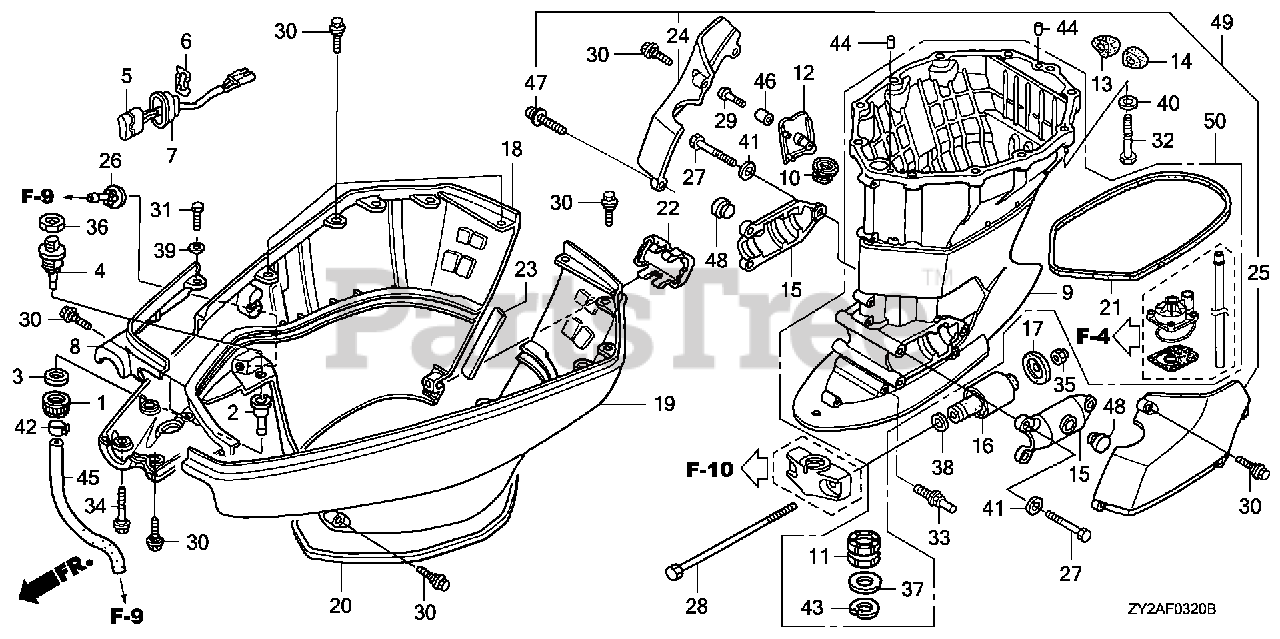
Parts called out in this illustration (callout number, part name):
1	NUT, WATER MOUTH
2	JOINT, WATER HOSE
3	SEAT, WATER MOUTH
4	CAP, WATER JOINT
5	SWITCH ASSY., POWER TILT
6	STAY, POWER TILT SWITCH
7	GROMMET, POWER TILT SWITCH
8	COVER, FR. SEPARATE *NH282MU* (OYSTER SILVER METALLIC-U)
9	CASE, EXTENSION *NH282MU* (XL) (OYSTER SILVER METALLIC-U)
10	RUBBER, DRAIN PLUG
11	BUSH, VERTICAL SHAFT
12	COVER, DRAIN PLUG *NH282MU* (XL) (OYSTER SILVER METALLIC-U)
13	SEAL, R. IDOL PORT
14	SEAL, L. IDOL PORT
15	HOUSING, MOUNTING (LOWER)
16	MOUNT, RUBBER (LOWER)
17	STOPPER, MOUNT (LOWER)
18	COVER, R. ENGINE (LOWER) *NH282MU* (OYSTER SILVER METALLIC-U)
19	COVER, L. ENGINE (LOWER) *NH282MU* (OYSTER SILVER METALLIC-U)
20	SEAL A, COVER (LOWER)
21	SEAL B, COVER (LOWER)
22	CAP, COVER (LOWER) *NH282MU* (OYSTER SILVER METALLIC-U)
23	SEAL C, COVER (LOWER)
24	COVER, R. MOUNTING (LOWER) *NH282MU* (XL) (OYSTER SILVER METALLIC-U)
25	COVER, L. MOUNTING (LOWER) *NH282MU* (XL) (OYSTER SILVER METALLIC-U)
26	GROMMET, WATER CHECK
27	BOLT, HEX. (10X35)
28	BOLT, HEX. (14X180)
29	SCREW, SPECIAL (6X35)
30	BOLT, SPECIAL (6X17)
31	BOLT, HEX. (6X25)
32	BOLT, HEX. (12X50)
33	BOLT, SPECIAL (6X12)
34	BOLT, SPECIAL (6X37)
35	NUT, SELF-LOCK (14MM)
36	NUT, HEX. (16MM)
37	WASHER (30MM)
38	WASHER, PLAIN (14MM)
39	WASHER (6MM)
40	WASHER, PLAIN (12MM)
41	WASHER, PLAIN (10MM)
42	CLIP, TUBE (B12.5)
43	CIRCLIP (INNER) (43)
44	PIN, DOWEL (6X10)
45	TUBE, WATER JOINT
46	COLLAR, DISTANCE (6X10.5X25)
47	SCREW, PAN (6X25)
48	RUBBER C, STAND STOPPER
50	CASE KIT, EXTENSION *NH282MU* (XXL) (OYSTER SILVER METALLIC-U)
